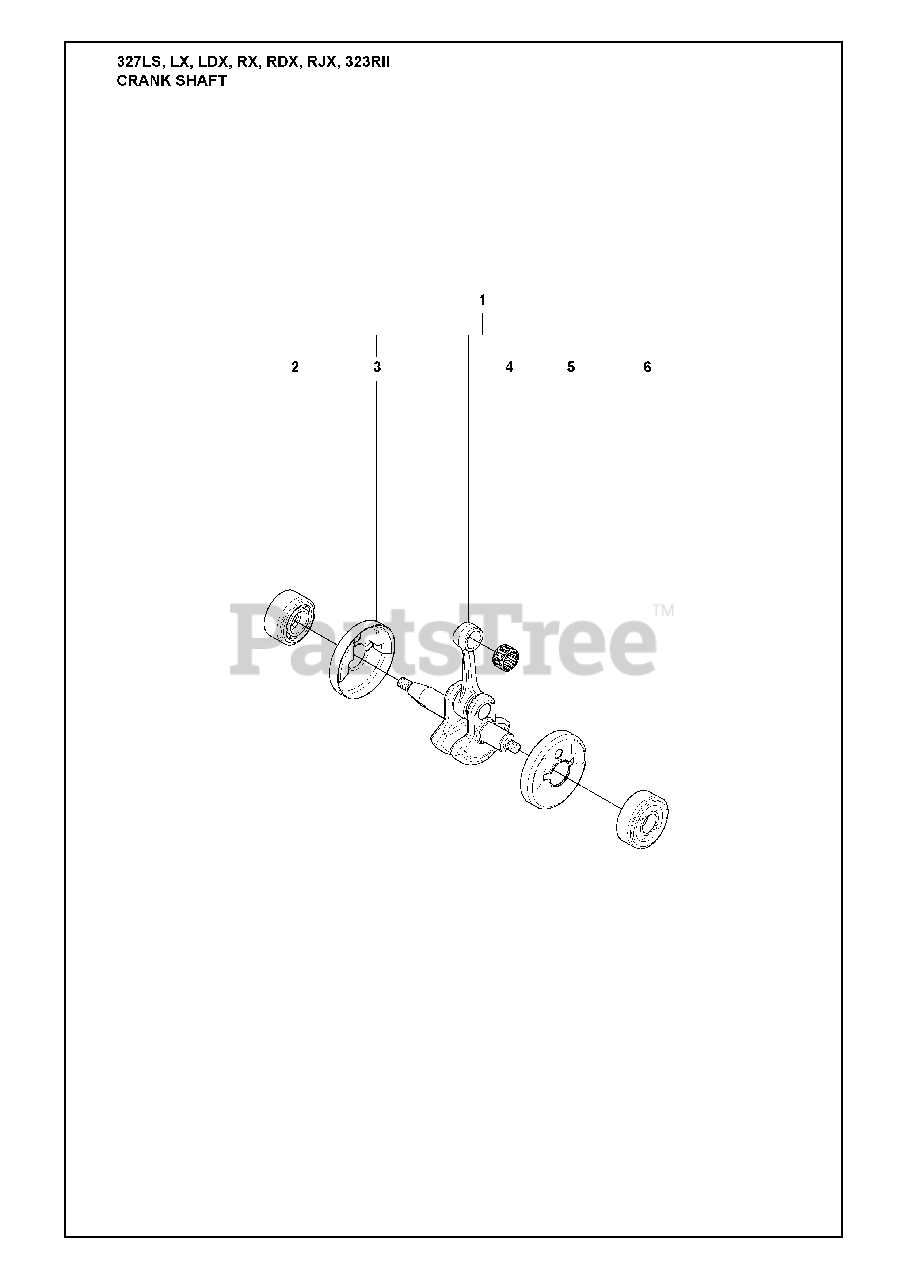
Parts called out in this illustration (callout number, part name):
1	CRANKSHAFT
2	BEARING CAP
6	BEARING CAP
